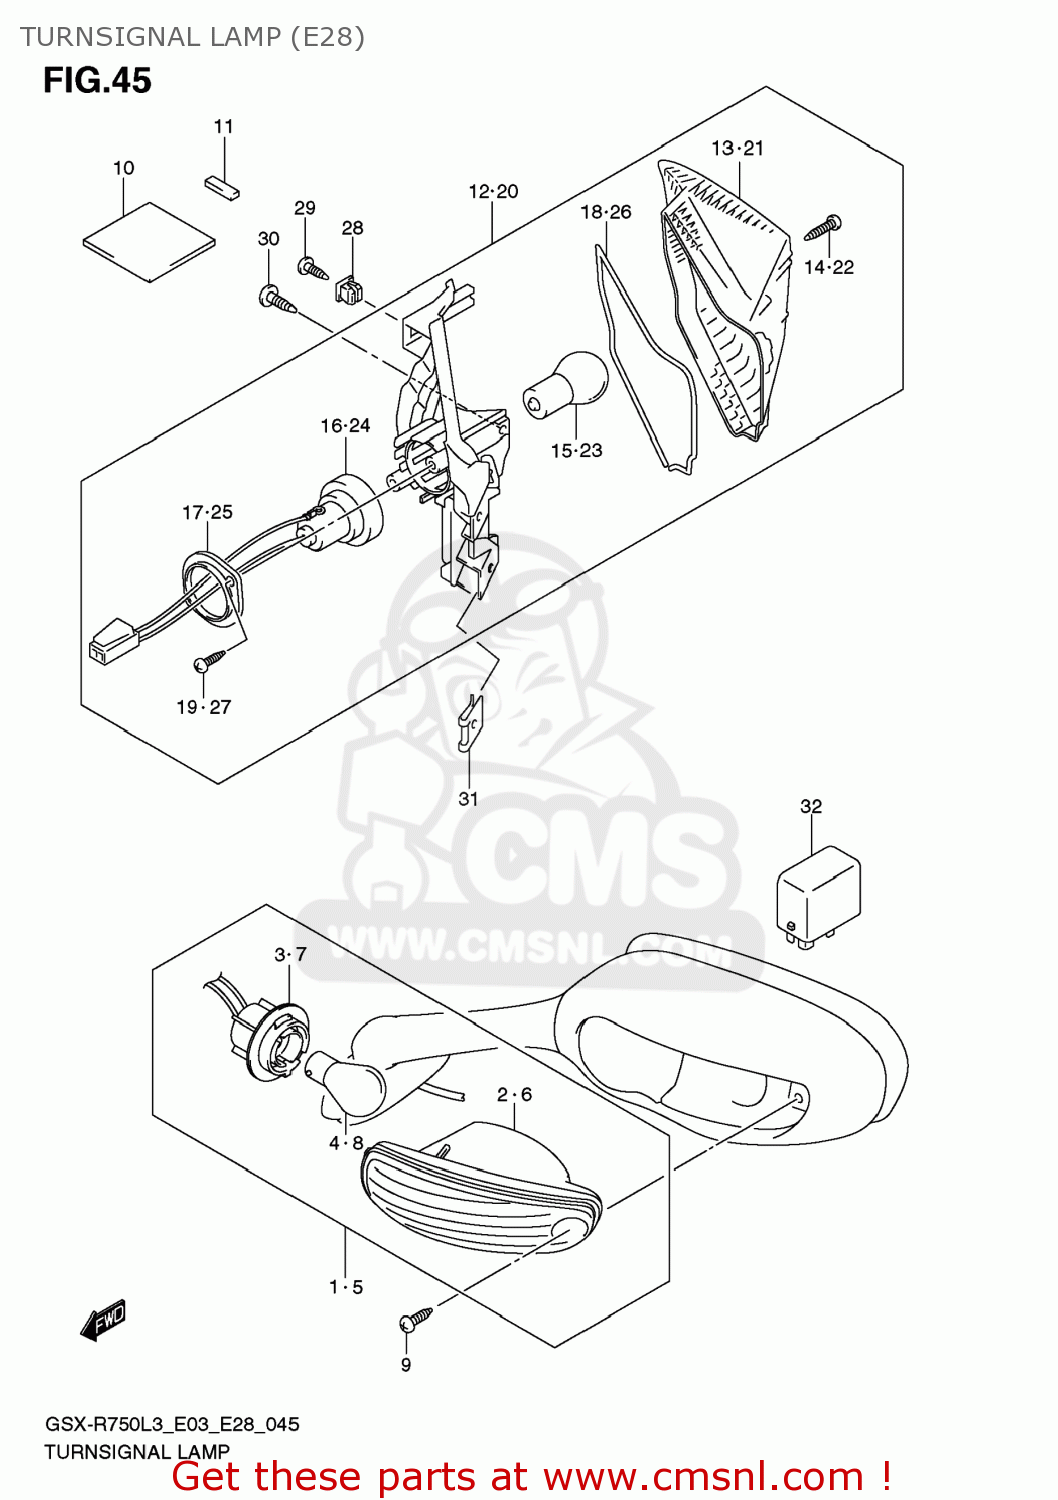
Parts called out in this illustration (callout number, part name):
1	LAMP ASSY,FR TURN SIGNAL,R
2	LAMP UNIT,R
3	SOCKET,R
4	BULB(12V21W,AMBER)
5	LAMP ASSY,FR TURN SIGNAL,L
6	LAMP UNIT,L
7	SOCKET,L
8	BULB(12V21W,AMBER)
9	SCREW(4X20)
10	CUSHION(40X20X5)
11	TAPE,FR TURNSIGNAL
12	LAMP ASSY,RR TURNSIGNAL,R
13	LENS,R
14	SCREW
15	BULB(12V21W,AMBER)
16	SOCKET & CORD,R
17	PLATE,RR COMBINATION
18	GASKET (NAS)
19	SCREW
20	LAMP ASSY,RR TURNSIGNAL,L
21	LENS,L
22	SCREW
23	BULB(12V21W,AMBER)
24	SOCKET & CORD,L
25	PLATE,RR COMBINATION
26	GASKET (NAS)
27	SCREW
28	NUT
29	SCREW
30	SCREW
31	NUT
32	RELAY ASSY,TURNSIGNAL LAMP
